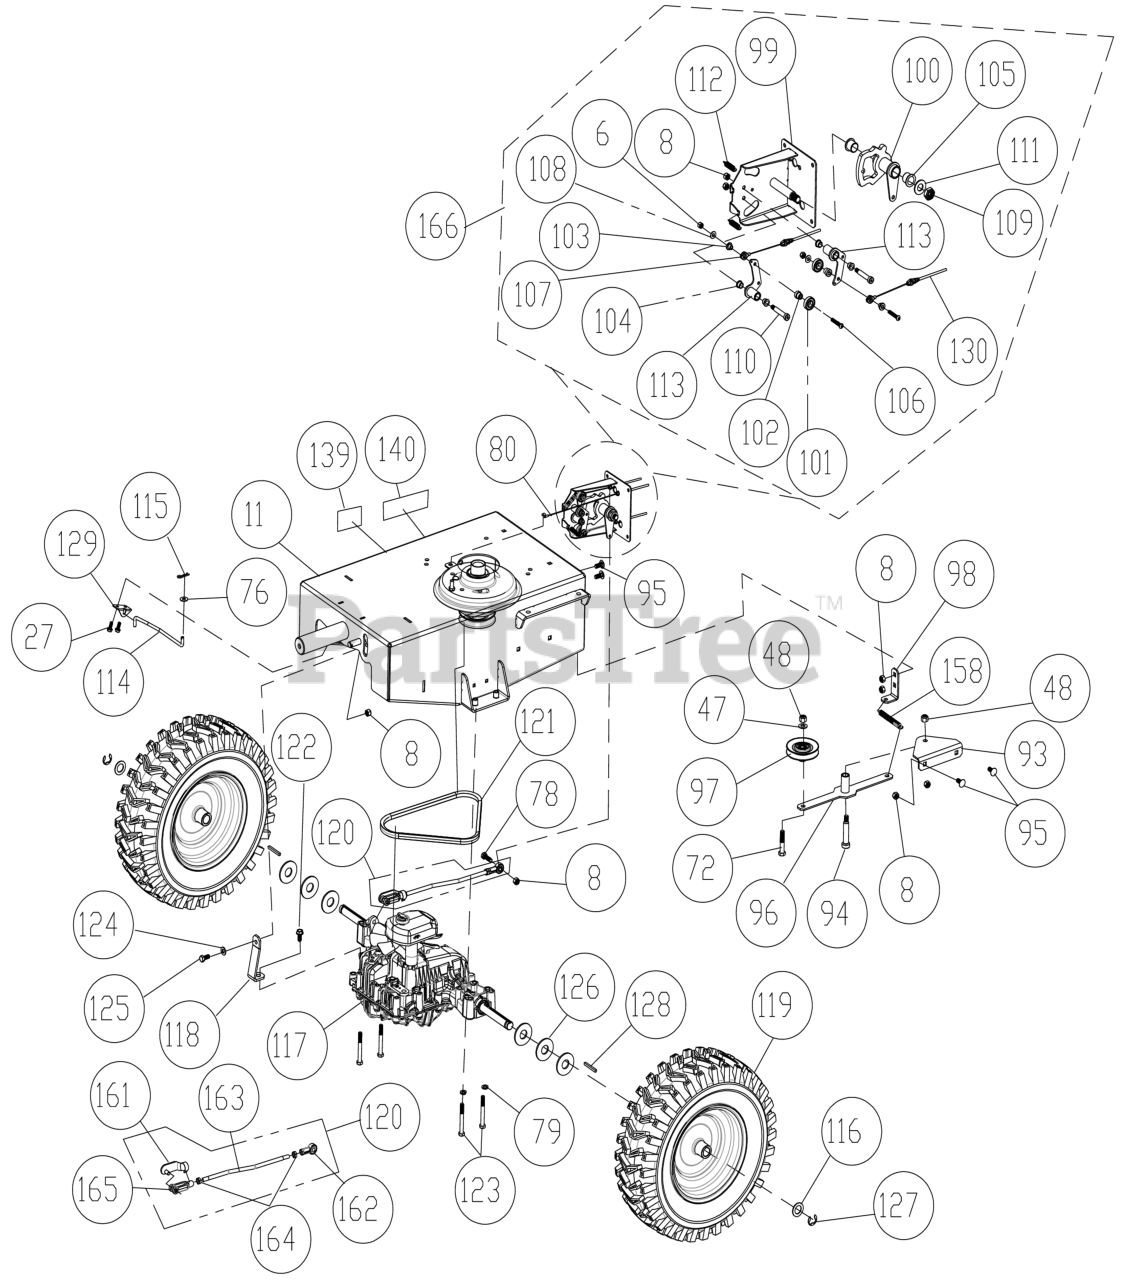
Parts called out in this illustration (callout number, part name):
6	NUT LOCK 1/4"-20 HEX Z/P
8	NUT LOCK 5/16"-18 HEX Z/P
11	ENGINE BASE WA W/LABELS
27	SCREW SELF TAP 1/4"-20 X 5/8" HWH TYPE F
47	WASHER 3/8"SAE 13/32"X13/16"X1/16"
48	NUT LOCK 3/8"-16 HEX
72	SCREWCAP 3/8"-16X2" HCS ZP
76	WASHER 1/4"SAE9/32"X5/8"X1/16"
78	SCREWCAP 5/16"-18 X 1" HCS ZP
79	WASHER LOCK 5/16 ST MED
80	CABLE CLUTCH
93	BRACKET IDLER ARM HYDRO BC26
94	BOLT SHOULDER 1/2" X 2"
95	BOLT CARRIAGE 5/16"-18 X 3/4" PLAIN
96	ARM IDLER DRIVE ENGAGE WA
97	PULLEY INSIDE IDLER BC26
98	BRACKET SPRING IDLER
99	BRACKET SPEED CONTROL BC26
100	CAM SPEED CONTROL WA
101	BEARING 1/2" ID X 1.125 OD
102	SPACER. SPEED CONTROL STEPPED PM
103	SPACER, SPEED CONTROL EYELET PM
104	BUSHING 3/8 ID X 1/2 OD X 3/8
105	BUSHING PIVOT FRAME AE
106	SCREWCAP 1/4-20 X 1 3/4 SKT BUT HD
107	CABLE SPEED CONTROL RT
108	WASHER 1/4"SAE9/32"X5/8"X1/16"
109	NUT LOCK 5/8"-11 LT WT TH Z/P
110	BOLT SHOULDER 3/8" X 1 3/4"
111	WASHER FLAT 5/8" SAE ZP
112	SPRING EXTENSION
113	BELLCRANK SPEED CONTROL BC26
115	PIN HAIR 1/4" Z/P
116	WASHER .765" ID X 1.25 OD X .06"
117	SEE: 501354
118	BRACKET SUPPORT HYDRO TRANSAXLE
119	WHEEL & TIRE AG 16" CENTERED HUB - FOAM (SEE ACCESSORY PRICELIST)
120	CONTROL ROD ASSEMBLY - SERVICE
121	BELT HYDRO TRANSAXLE BC26
122	SCREW SELF TAP 5/16" X 3/4" HEX
123	SCREWCAP 5/16"-18X2 3/4" HCS ZP
124	WASHER 5/16" SAE Z/P
125	SCREWCAP 5/16"-18X3/4" HCS ZP
126	WASHER 3/4" SAE 13/16"X1.5"X1/8"ZP
127	RING RETAINING "E" 3/4"
128	KEY 3/16" SQ X 2 1/8"
129	BRACKET BYPASS ROD
130	CABLE SPEED CONTROL LFT
139	LABEL DRIVE RELEASE
140	LABEL CHOCK WHEELS
158	SPRING IDLER BC
161	SPRING PIN, CONTROL ROD
162	SPHERICAL ROD END MSF-5
163	CONTROL ROD BC2600
164	NUT JAM 5/16" NC
165	YOKE FEMALE STEEL 5/16-20 RH X 2.25
166	SPEED CONTROL ASSY NO CABLES BC26
